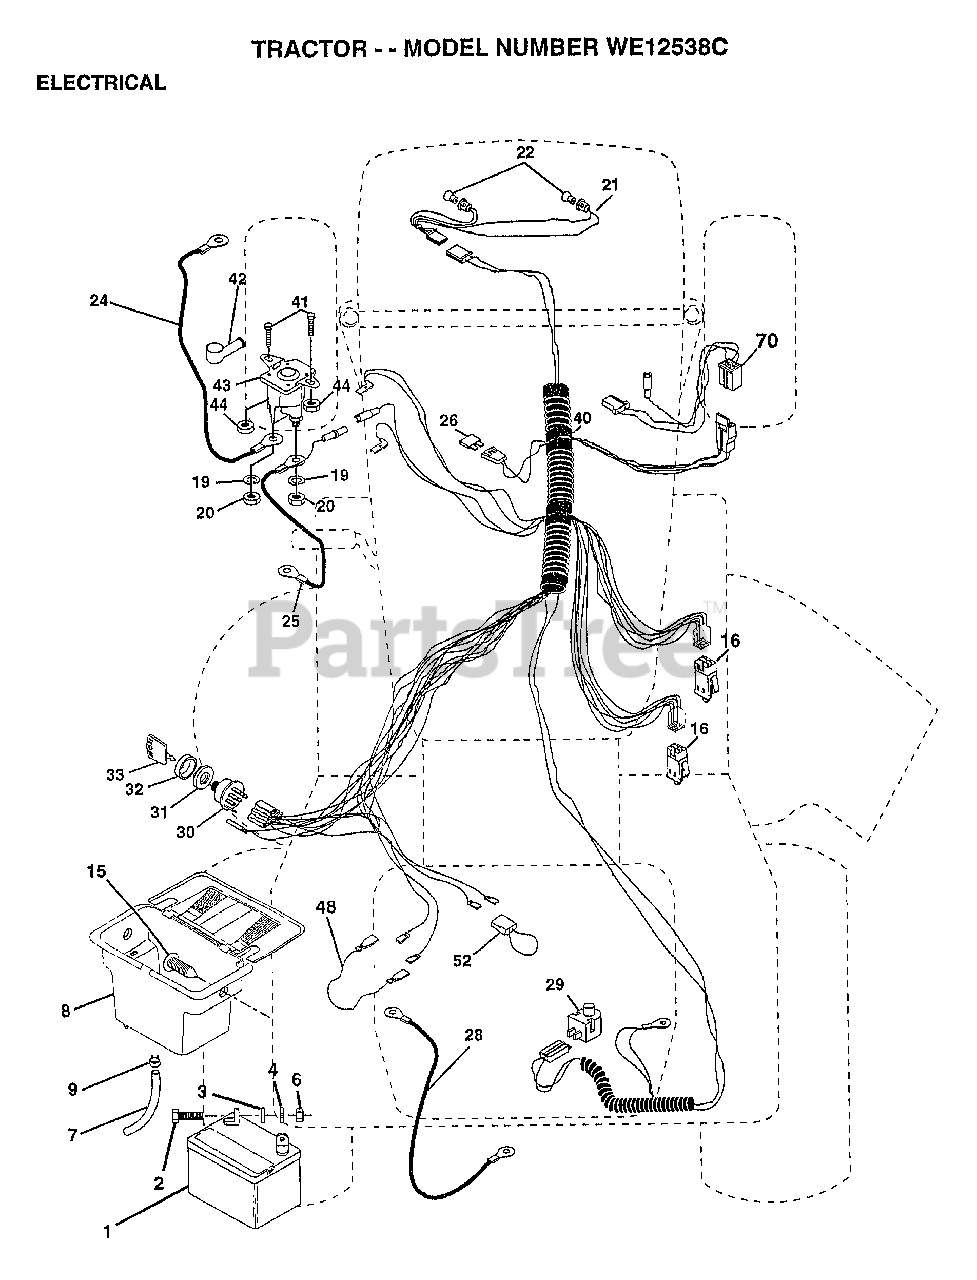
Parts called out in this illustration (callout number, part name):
2	BOLT LT
3	WASHER
4	LOCKWASHER
7	TUBE T
8	"CASE,BATTERY.MECH"
9	HOSE CLAMP T
15	FASTNER.SNAP-IN
16	SWITCH INTERLOCK
20	NUT
21	"HARNESS,LIGHT SOC"
22	HEADLAMP BULB
24	"CABLE T, BATTERY"
25	CABLE.BTRY.6GA.RD
26	FUSE HYT
28	CABLE T
29	SWITCH SEAT
30	SWITCH IGN 4POS
31	NUT IGNITION
32	COVER KEY SWITCH
33	KEY
40	HARNESS-IGNITION
41	BOLT HXHD FIN
44	NUT HXKEP 1/4X20
48	ADAPTER AMMETER
52	PROTECTION LOOP
70	HARNESS ENG DUAL
